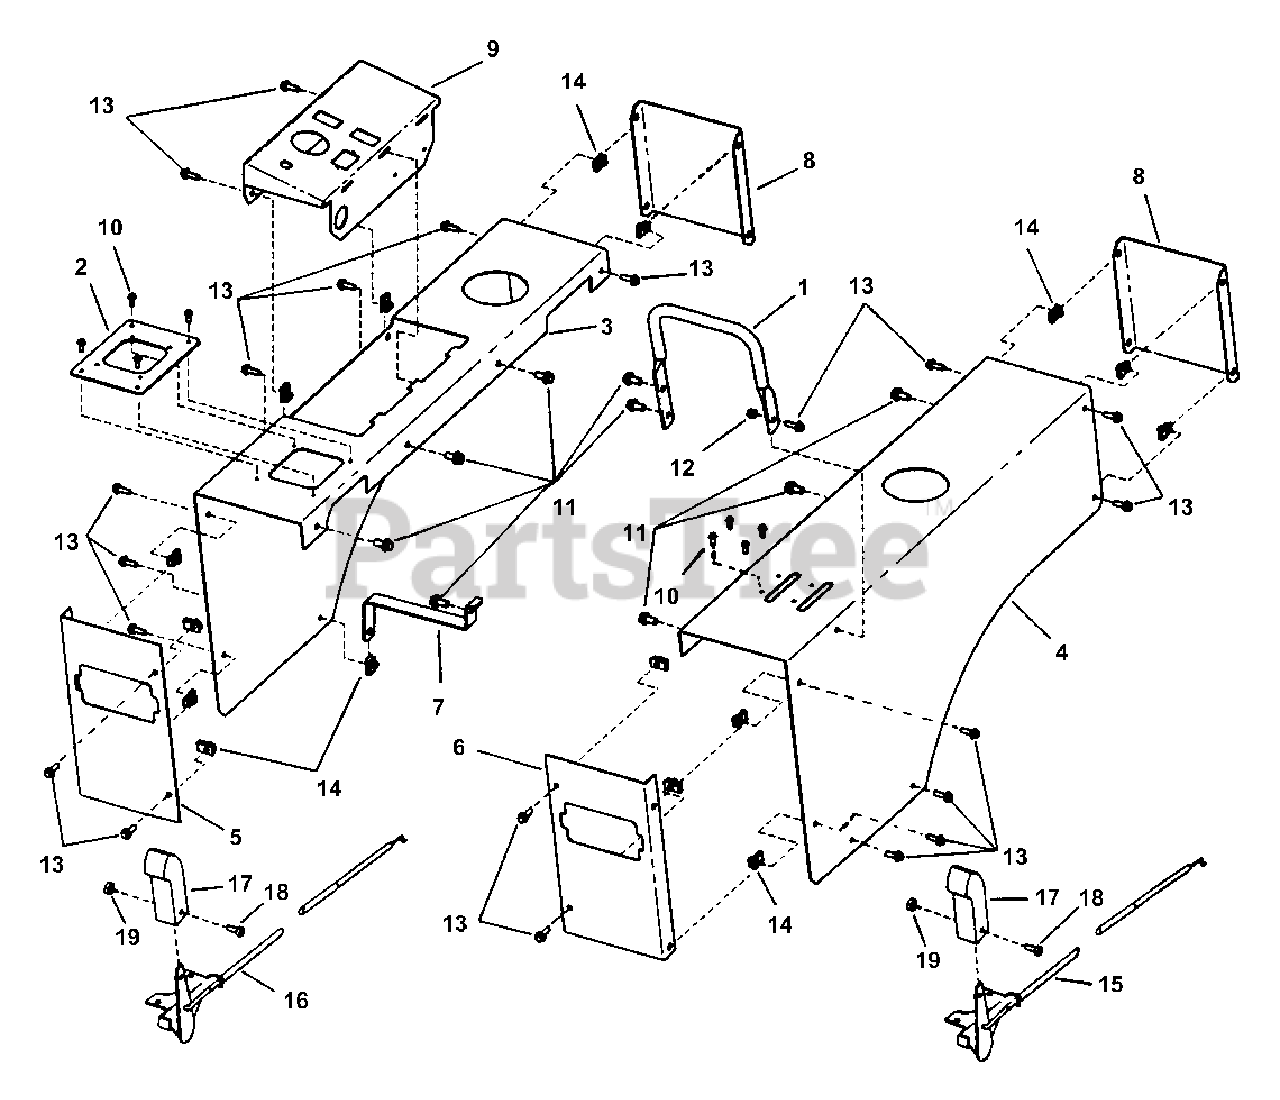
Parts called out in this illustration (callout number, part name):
1	HANDLE, 5/8" Tubing
2	PLATE, Joystick Control
3	FENDER, Right Hand
4	FENDER, Left Hand
5	BRACKET, R. H. Headlight
6	BRACKET, L. H. Headlight
7	BRACKET, Fender Brace
8	BRACKET, Rear Fender
9	BRACKET, Instrument Panel
10	SCREW, #10-24 x 1/2" Hex Washer Self-Tap (Torx)
11	SCREW, 5/16-18 x 5/8" Hex Washer Self-Tapping
12	NUT, 1/4-20 HEX NYLON LOCK
13	SCREW, 1/4-20 x 3/4" Hex Cap Grade 5
14	U-NUT, 1/4-20 Lock,
15	CABLE, Choke, Kohler
16	CABLE, Throttle, Kohler
17	LEVER, Throttle Control
18	SCREW, #8-32 x 3/8" Curved Machine
19	NUT, #8-32 Hex
